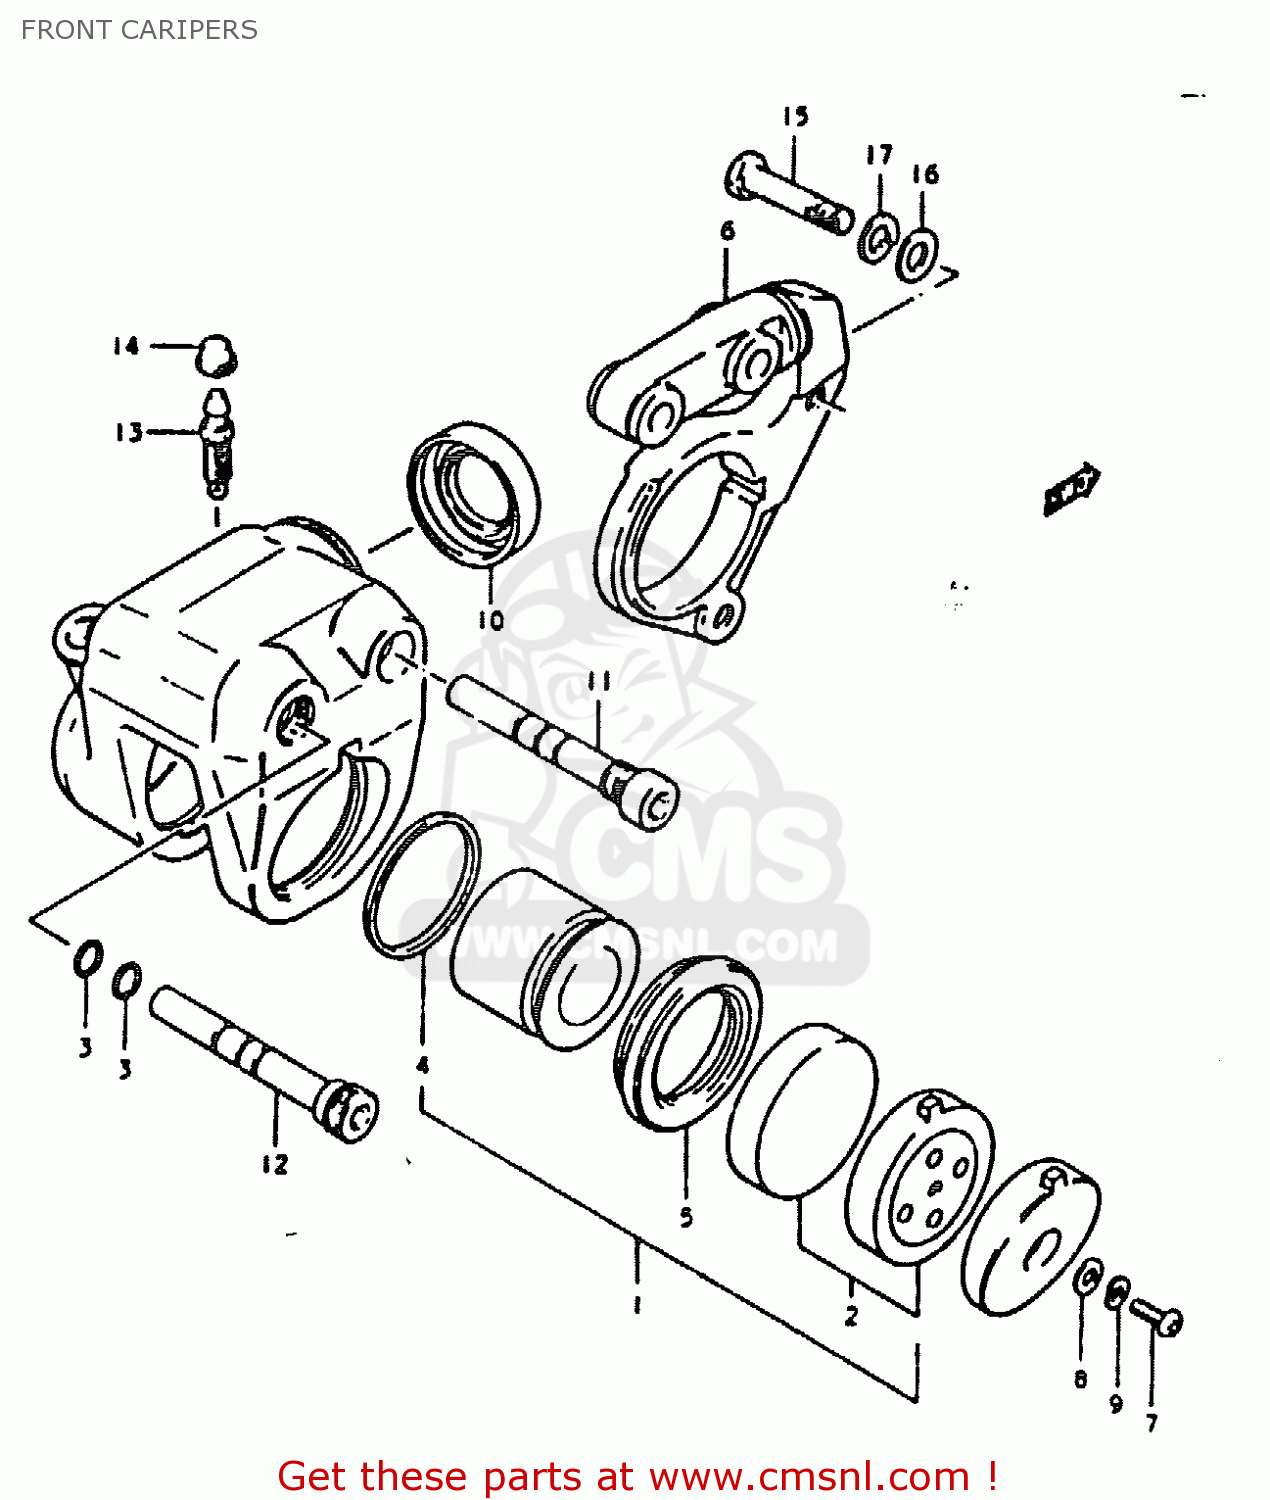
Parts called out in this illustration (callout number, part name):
1	PISTON & PAD SET
2	PAD SET (MCA)
3	O RING,AXLE CALIPER
4	SEAL,PISTON
5	BOOT,PISTON
6	HOLDER,CALIPER
7	SCREW
8	WASHER
9	LOCK WASHER
10	BOOT,HOLDER
11	AXLE,CALIPER
12	AXLE NO.2
13	BLEEDER
14	CAP,BLEEDER PL
15	BOLT
16	WASHER
17	LOCK WASHER
